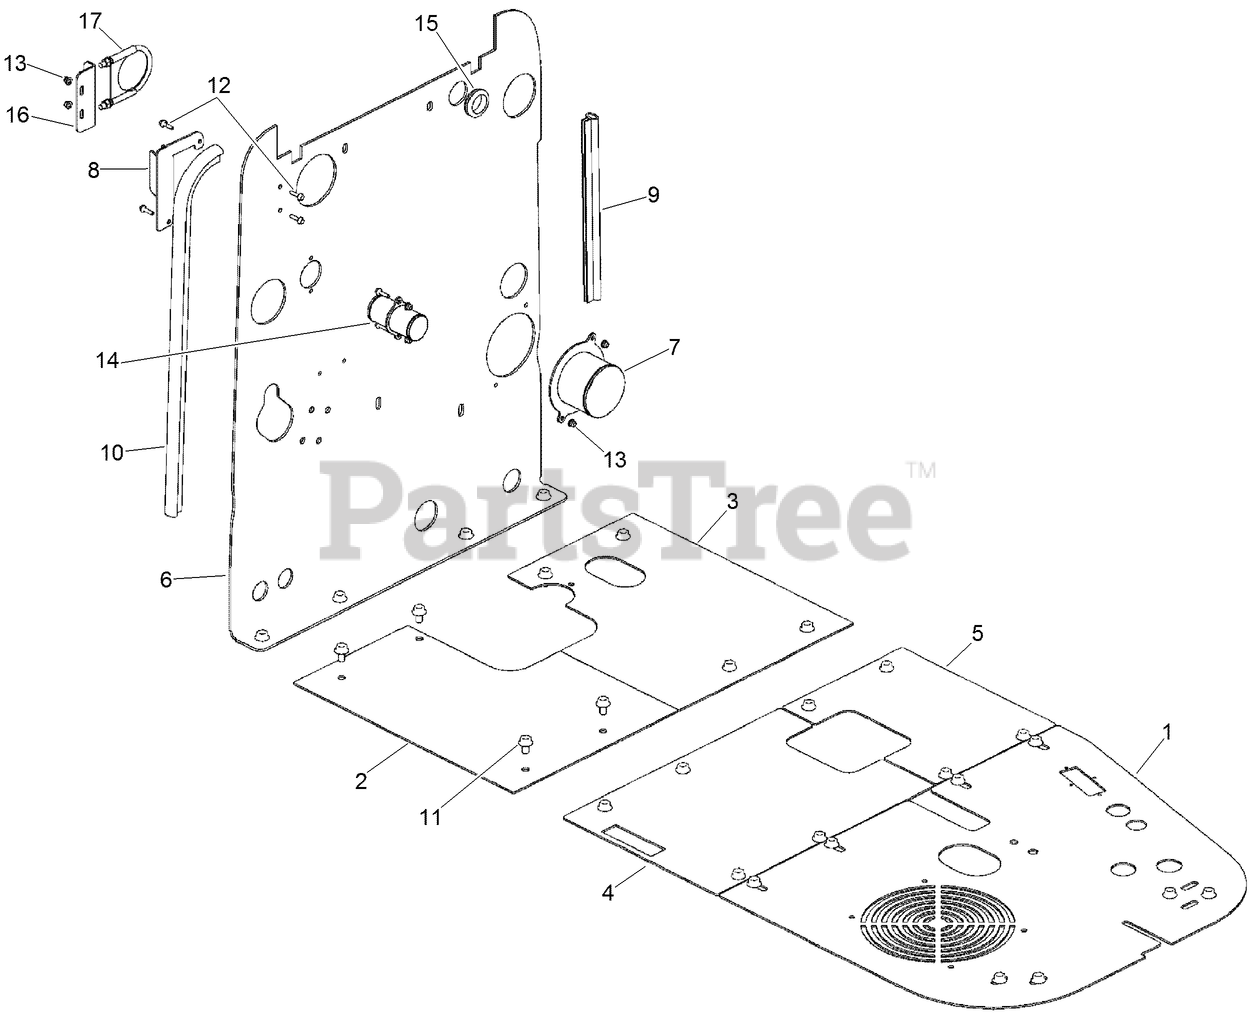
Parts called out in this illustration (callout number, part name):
1	PLATE - Hood Seal
2	PLATE - Hood Seal
3	PLATE - Hood Seal
4	PLATE - Hood Seal
5	PLATE - Hood Seal
6	PLATE - Bulkhead
7	MOUNT - Fresh Air Intake
8	PLATE - Air Intake, Heat Deflector
9	SEAL - Bulb, 389 mm Cut Length
10	SEAL - Bulb, 775 mm Cut Length
11	SCREW, METRIC FLANGE FULL - M12 x 20
12	SCREW, METRIC FLANGE w/BODY-M6 x 25
13	NUT, METRIC FLANGE PREVAILING - M6 Zinc
14	BULKHEAD - Radiator
15	GROMMET - Rubber, 1.5 ID
16	PLATE - Exhaust Support
17	CLAMP-GUILLOTINE
